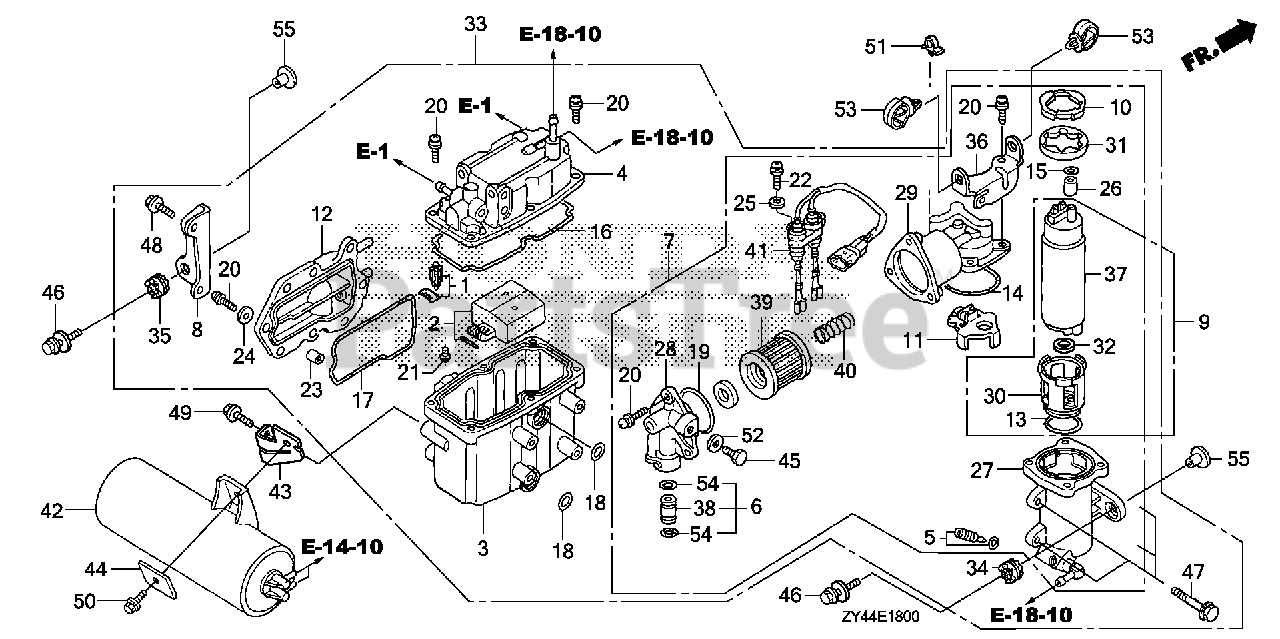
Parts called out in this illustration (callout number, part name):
1	VALVE SET, FLOAT
3	BODY
5	SCREW SET, DRAIN
7	PUMP UNIT, FUEL (MSDS)
8	STAY, PLATE
9	PUMP UNIT SET B, FUEL (MSDS)
12	COVER, WATER JACKET
15	O-RING
15	O-RING (7.3X2.2) (NOK)
20	SCREW-WASHER
21	SCREW, PAN
22	SCREW, WASHER
23	COLLAR, SET
24	WASHER, PLAIN
25	WASHER, PLAIN
27	CASE, PUMP
28	COVER, PUMP
29	COVER, PUMP
33	SEPARATOR ASSY., VAPOR
34	GROMMET, VAPOR SEPARATOR
35	GROMMET, VAPOR SEPARATOR
36	STAY, PLATE
37	PUMP UNIT, FUEL (MSDS)
38	JOINT, FUEL PIPE
39	SCREEN, FUEL STRAINER
40	SPRING, SET
42	TANK, VACUUM
43	STAY, VACUUM TANK
45	BOLT, SEALING (6MM)
46	BOLT-WASHER (8X35)
47	BOLT, FLANGE (6X25)
48	BOLT, FLANGE (6X16)
49	BOLT, FLANGE (6X14)
50	BOLT, FLANGE (6X12)
51	HOLDER, ROD (6MM)
52	WASHER, SEALING (6MM)
53	CLIP, HARNESS
54	O-RING (7.8X1.9) (ARAI)
55	COLLAR (8.5X14.5)
